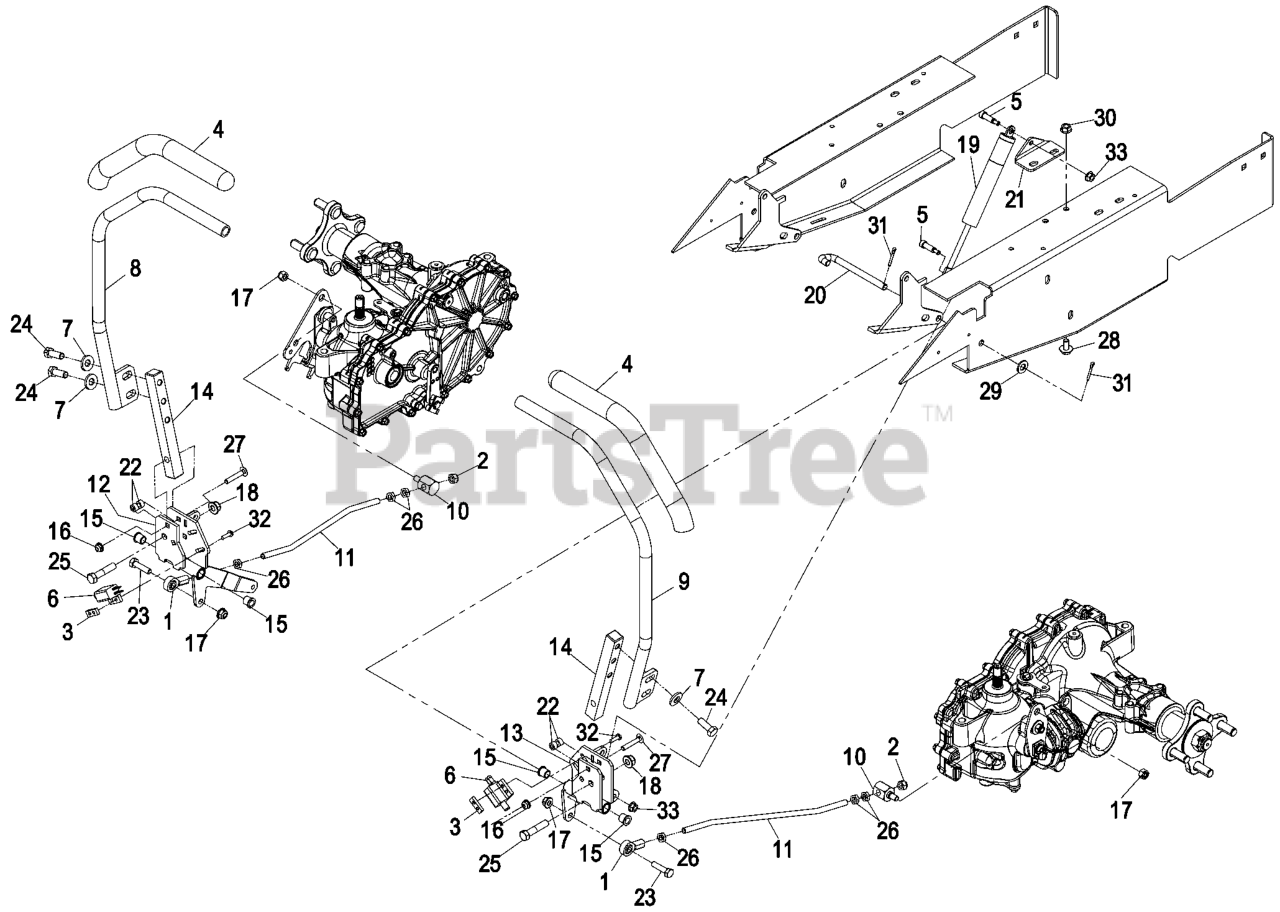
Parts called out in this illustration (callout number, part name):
1	BALLJOINT-RH
2	NUT-LOCK
3	PLATE-TAPPED
4	GRIP-CONTROL, MOTION
5	SCREW-HSH
7	WASHER-BELLEVILLE
8	ASM,LEVER CONTROL RH
9	ASM,LEVER CONTROL LH
10	TRUNNION
11	ROD-STEERING, LH
12	CONTROL-STEERING, RH
13	CONTROL-STEERING, LH
14	MOUNT-POST, LEVER
15	BEARING
17	NUT-HF, NI
18	NUT-HF, NI
19	DAMPER-CONTROL, MOTION
20	SHAFT-PIVOT, CONTROL
21	BRACKET-DAMPER
23	SCREW-HH
24	SCREW-HH
25	SCREW-HH
26	NUT-JAM
27	SCREW-CARR
28	SCREW-HHF
29	WASHER-FLAT
31	PIN-COTTER
32	SCREW-PPH
